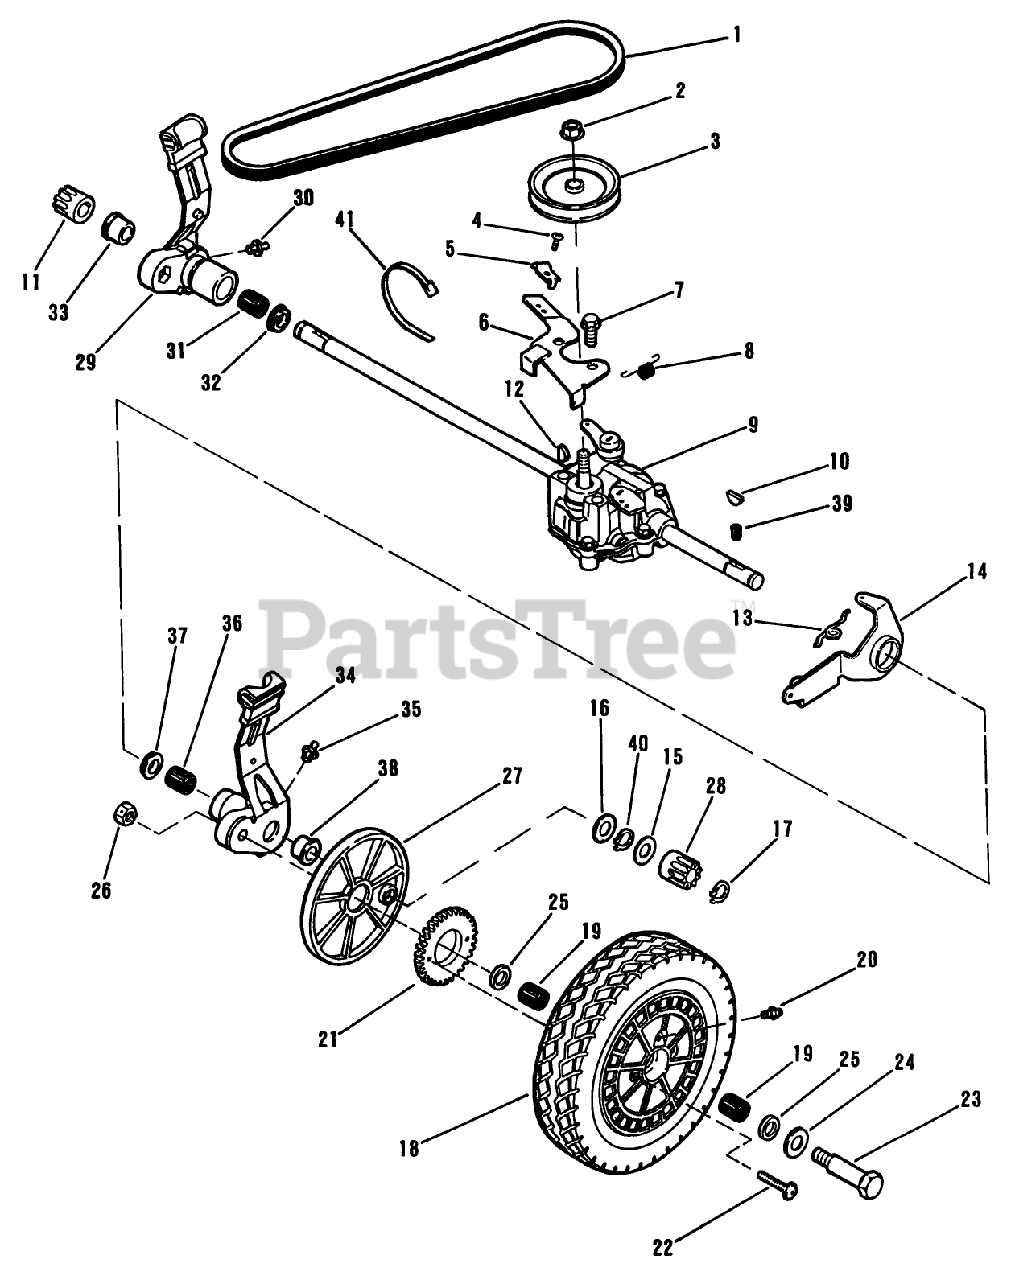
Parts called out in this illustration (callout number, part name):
3	PULLEY TRANS ADAMS
5	CLAMP-CABLE
8	SPRING-EXTENSION
9	TRANSMISSION ASSEM
10	KEY
11	PINION(R)MET ALLEG
12	KEY GALGER
13	LINK
15	THRUST WASHER
16	WASHER-THRUST
17	RETAINING RING
20	FITTING LINCOLN
22	SCREW-PH
23	BOLT WHEEL QUAL
24	SPACER
25	WASHER
26	LOCKNUT
27	COVER-WHEEL
28	PINION(L)MET ALLEG
30	**FITTING LINCOLN
32	SEAL CR IND
35	**FITTING LINCOLN
37	SEAL CR IND
39	SPRING
40	RET RING
